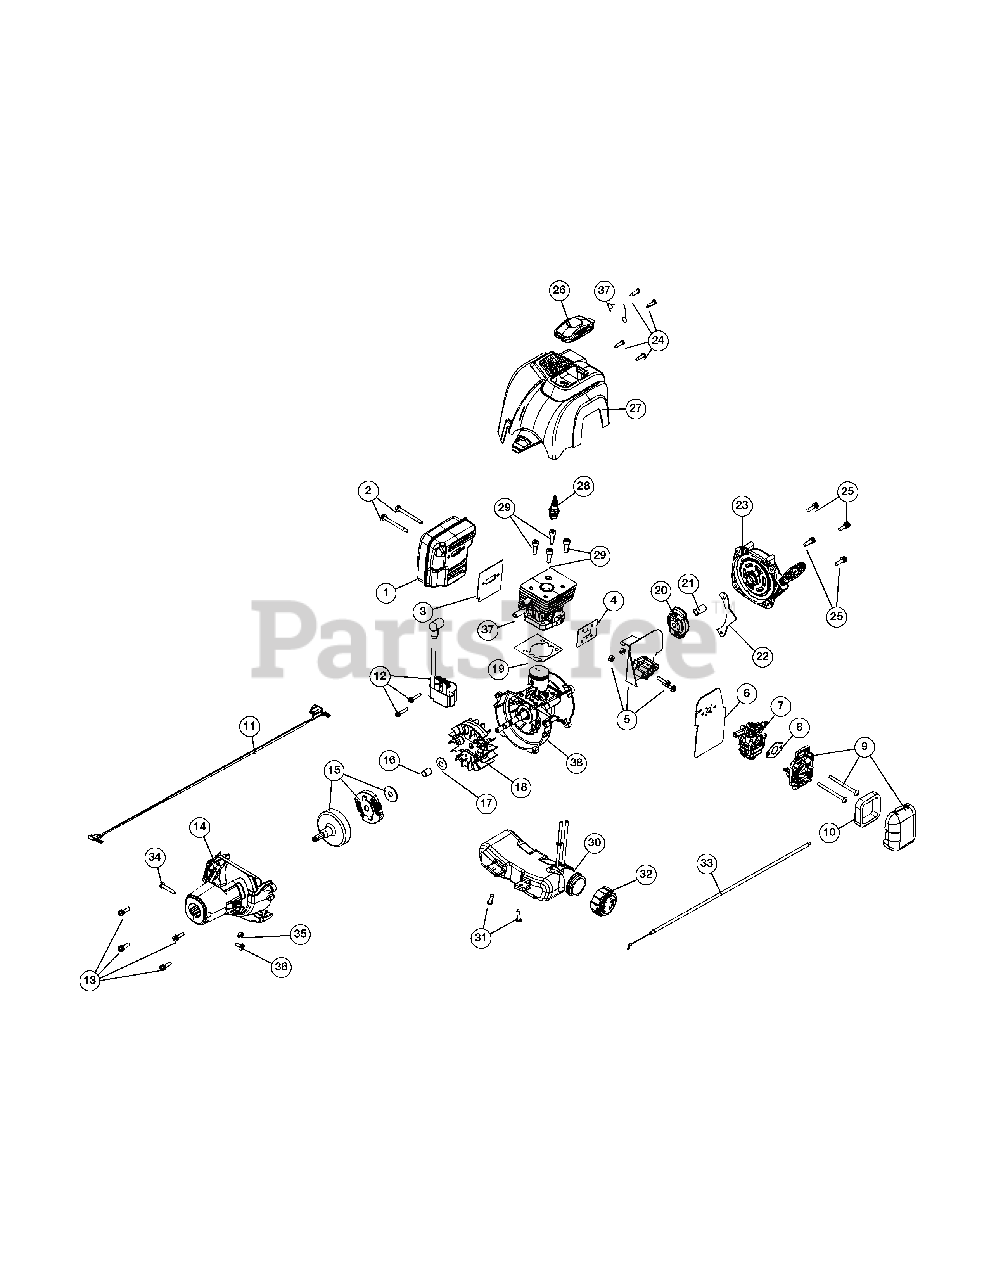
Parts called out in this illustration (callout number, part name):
1	Muffler Assembly
2	Muffler Bolts
3	Muffler Gasket
5	Insulator Assembly
6	Heat Shield
7	Carburetor
8	Carburetor Gasket
9	Aircleaner Assembly
10	Aircleaner Filter
12	Module Assembly
13	Clutch Cover Screws
14	Clutch Cover Assembly
15	Clutch Assembly
18	Flywheel Assembly
19	Cylinder Gasket
20	Pawl Assembly
21	Electric Starter Adapter
22	Starter Cover Guard
23	Starter Assembly
26	Spark Plug Cover
27	Engine Cover
28	Spark Plug
29	Cylinder Screws
30	Fuel Tank Assembly
31	Fuel Tank Screws
33	Throttle Cable
34	Screw
36	Anti-Rotation Screw
37	Wire Guard
38	Shortblock
